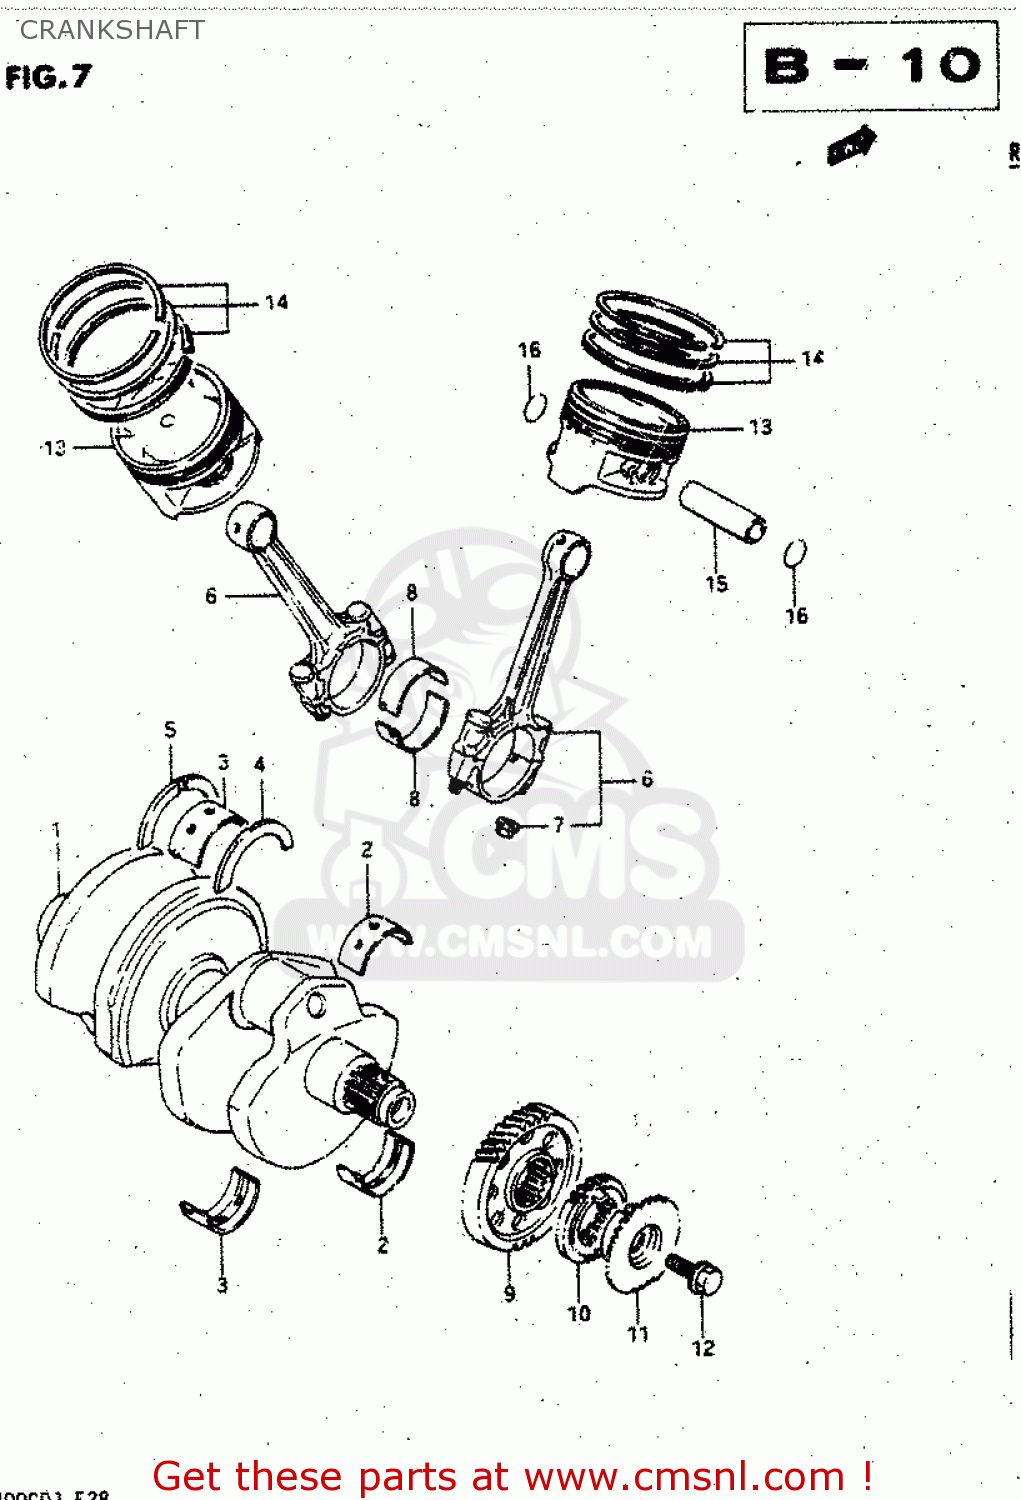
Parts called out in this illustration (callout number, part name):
1	CRANKSHAFT
2	METAL CRANKSHAFT
3	METAL CRANKSHAFT
4	PLATE,CRANK THRUST
5	PLATE,CRANK THRUST
6	CONNECTING ROD ASSEMBLY
7	NUT
8	BEARING,CRANK PIN
9	GEAR,PRIMARY DRIVE
10	SPROCKET,CHAIN DRIVE I
11	SPROCKET,WATER PUMP DRIVE
12	BOLT(10X24)
13	PISTON
14	RING SET,PISTON
15	PIN,PISTON
16	CIRCLIP,PISTON PIN
